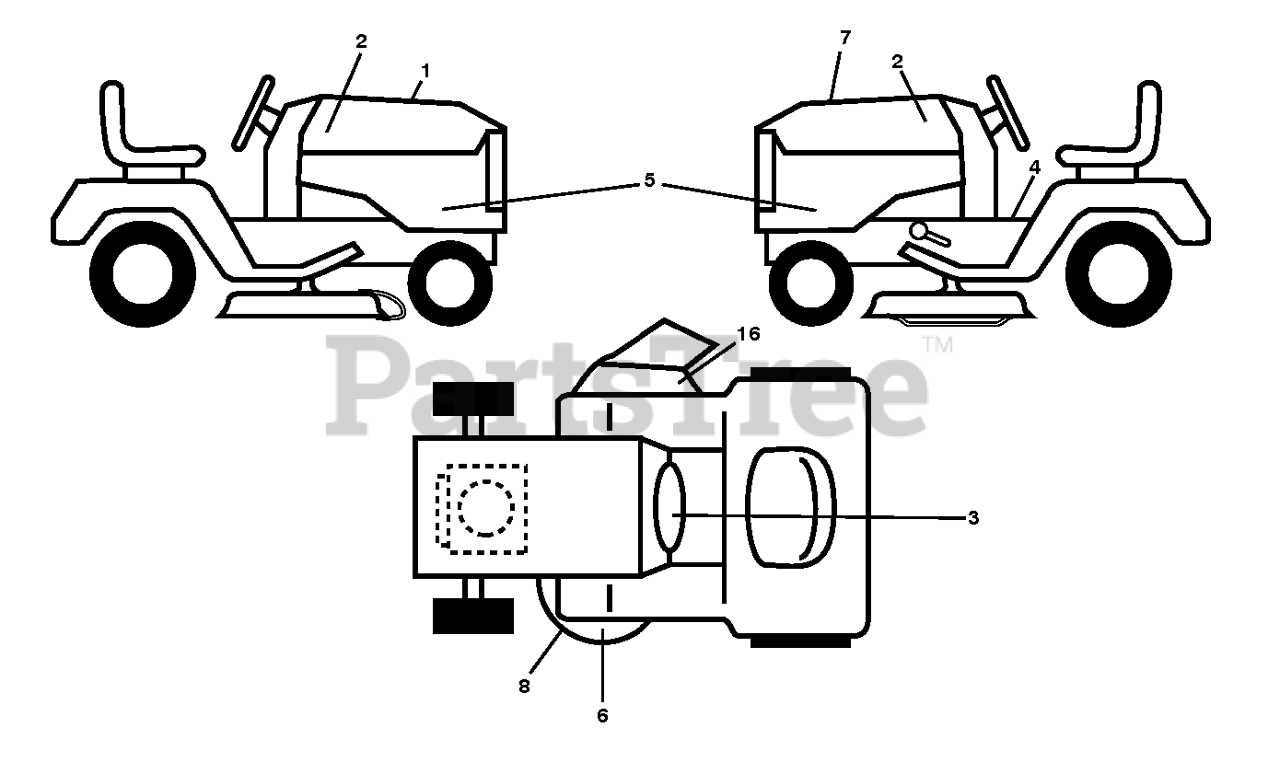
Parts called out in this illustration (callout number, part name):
1	DECAL RPL.VATR.KOH590-3022.42C
2	DECAL.BADGE.170MM.TEXTLOGO.
3	DCL.WARNING.SPARK.IGNITION.CA
4	DECAL.WARNING.2007.ENG/FR
5	DECAL.SIDE.PANEL.YTA19K42
6	DECAL POP ARMORPROTECTORDECK
7	DECAL.WARNING.CUST.RESP.E85.
8	DECAL.V-BELT.SCH.42/46"MEC/ELE
16	DECAL, DECK DEFLECTOR, WARNING
